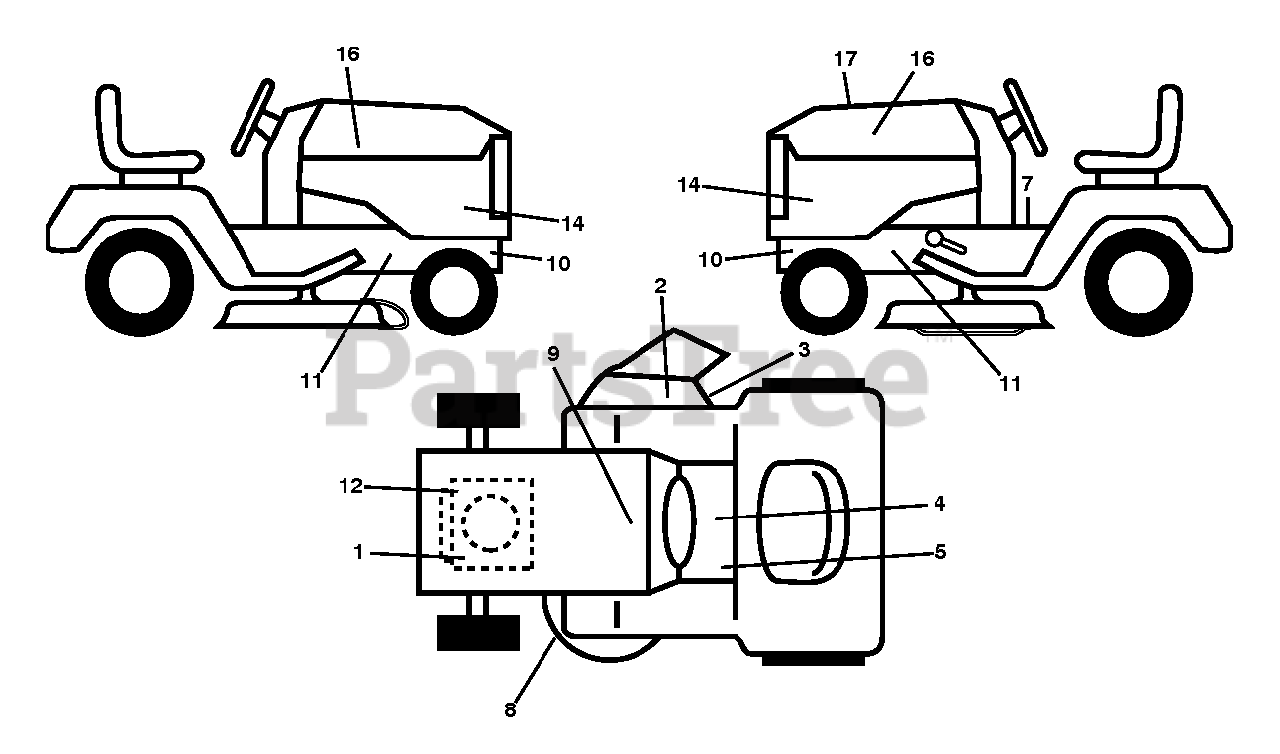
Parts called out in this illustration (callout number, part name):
1	DECAL.ENG.BS.656.ENDUR.382292
2	DECAL, DECK DEFLECTOR, WARNING
3	DECAL.DFLCTR.WARNNG.CTFNGR.SYM
4	DECAL.PARKING.BRAKE.SADDLE.LT
5	DECAL.FNDR.SDLE.BRAKE.CLUTCH.6
7	DECAL.READ.OWN.MAN.SYMBOL.LT
8	DECAL.V-BELT.SCH.42/46"MEC/ELE
9	DECAL BTRY SYMBOLS
10	DECAL.CHASSIS.HOT.MUFFLER
11	DECAL.WARNING.SERVCE/FIRE
12	DECAL.ENGINE.WARNING
14	DECAL.SDPNL.HUSQGT.TS243.RH/LH
16	DECAL.BADGE.170MM.TEXTLOGO.
17	DECAL.RPL.BSM40.END.TLW.42.K46
